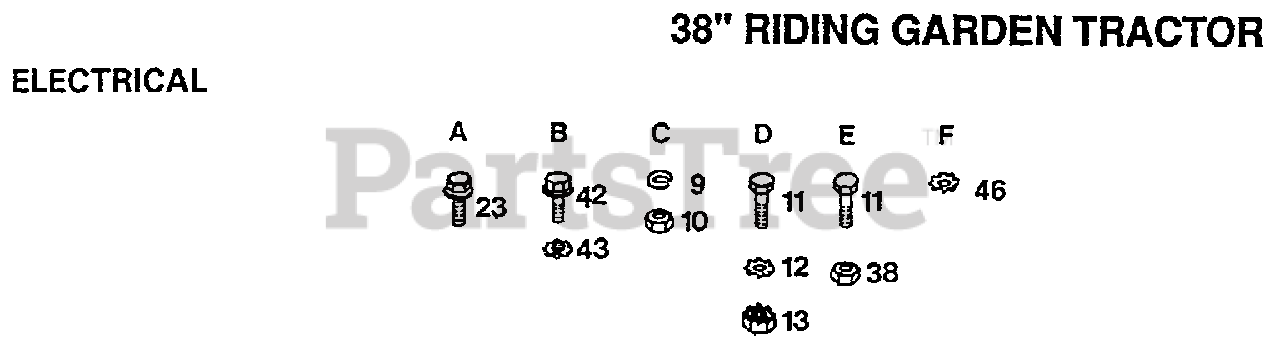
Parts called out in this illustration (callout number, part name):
10	NUT
11	BOLT
13	NUT
23	SCREW
42	SCREW
43	"NUT,KEPS"
46	LOCKWASHER
